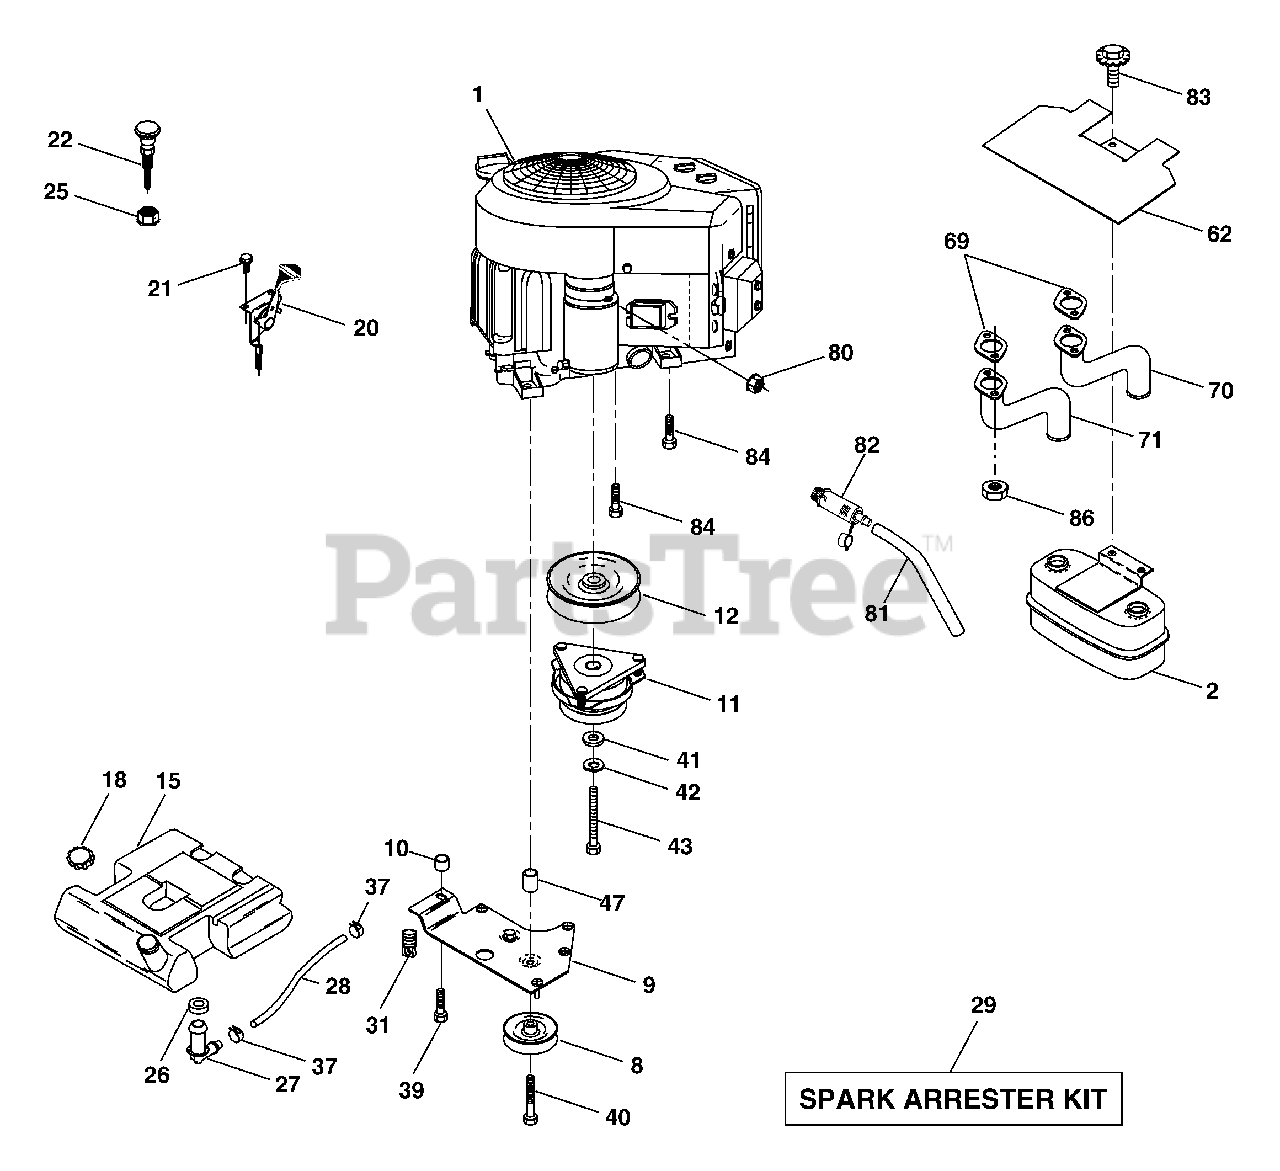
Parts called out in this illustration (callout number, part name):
2	Muffler Side
8	Pulley V-Idler
9	Keeper Asm. Belt Engine VGT
11	Clutch Electric
12	Pulley Engine VGT Elect Clutch
18	Cap Fuel
20	Control Throttle
21	Screw HWHD Hi-Lo #13-16 x 3/4
22	Control Choke
25	Nut Keps 3/8-24 unf
26	Bushing
27	Stem Tank Fuel
28	Fuel Line
29	Spark Arrester Kit
31	Clip Push-In Hinged
37	Clamp Hose
39	Screw TT 3/8-16 x 2-1/4 unc
40	Screw TT 3/8-16 x 4 unc
41	Washer 1-1/2 OD x 15/32 ID x .250
42	Washer Lock 7/16
43	Bolt Hex 7/16-20 X 3.75 Gr. 5
62	Shield Heat Muffler
69	Gasket
70	Tube Exhaust RH
71	Tube Exhaust LH
80	Nut Flange M8-1.25
81	Tube Drain Oil Easy
82	Valve Oil Drain (Order from engine mfg.)
83	Bolt 5/16-18 unc x 1-3/4 W/Sems
84	Screw 3/8-16 x 1-1/2
86	Nut Hex Flange Toplock M8-1.25
